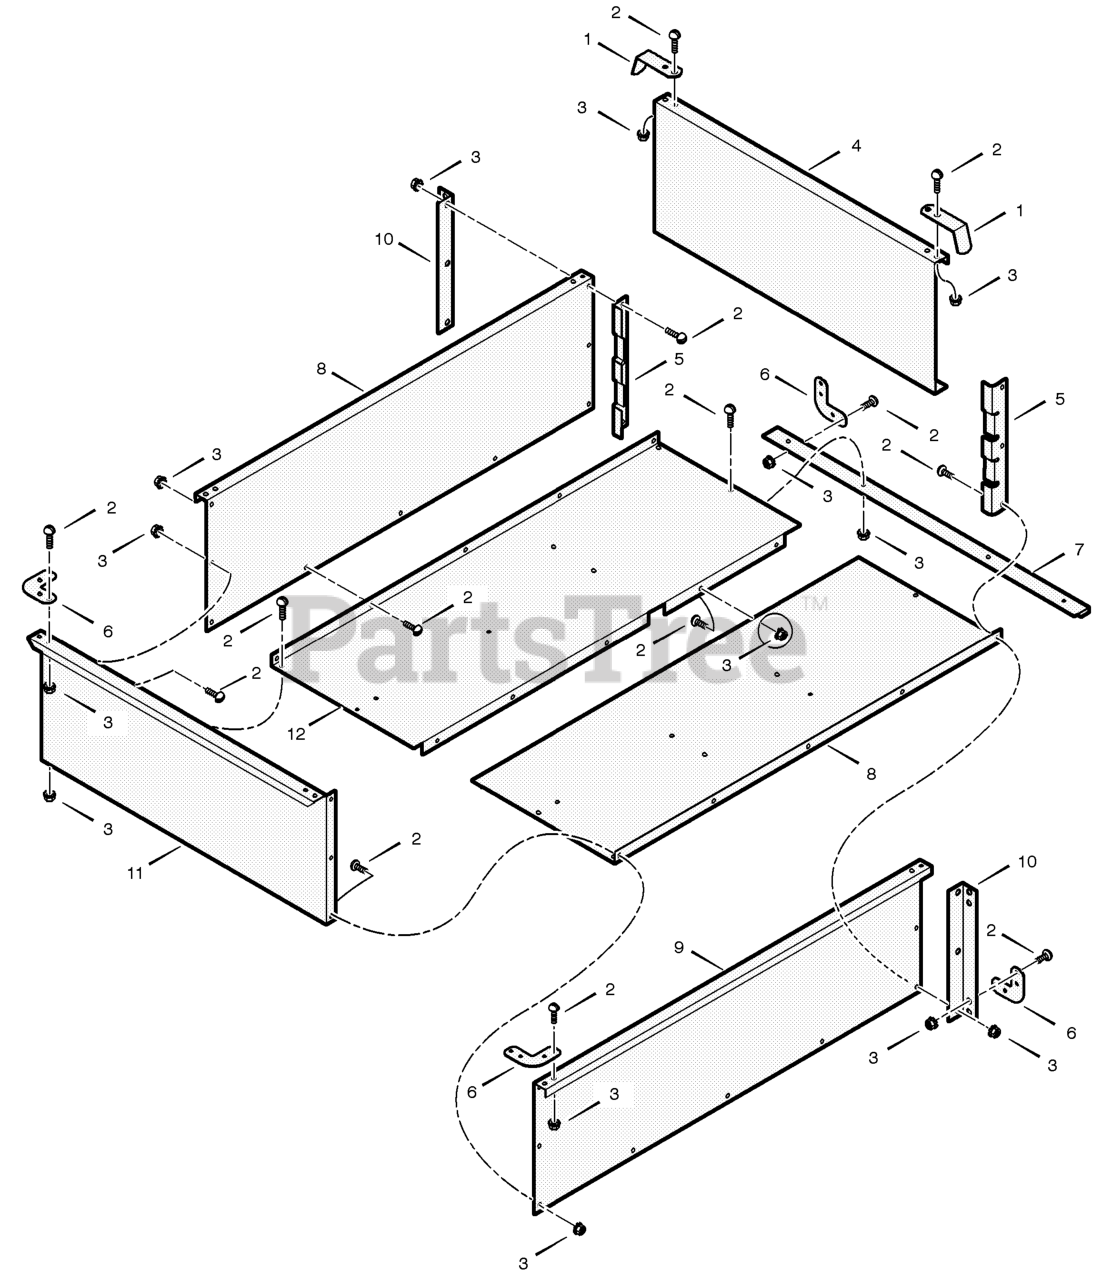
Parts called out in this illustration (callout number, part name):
1	Support, Side
2	Screw 1/4-20x0.50
3	Nut, Keps 1/4-20
4	Tailgate (Black)
5	Retainer, Tailgate
6	Bracket, Corner
7	Brace, Rear
8	Bottom, Right
9	Panel, Side (Black)
10	Support, Side
11	Panel, Front
12	Bottom, Left
